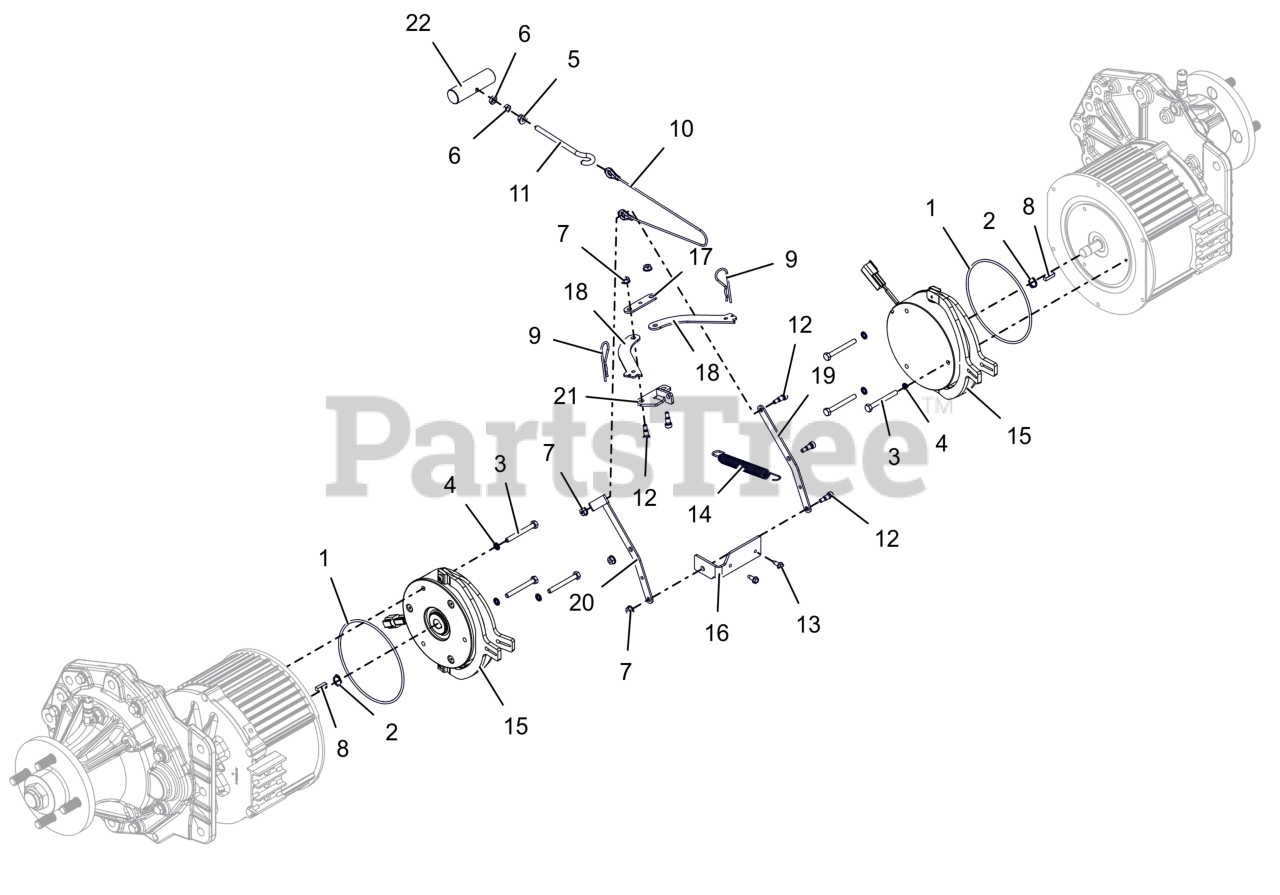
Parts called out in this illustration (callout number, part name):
1	O-RING 126MM IDX3MM
2	RING, RETAINING-EXTERNAL 25MM X 1.2MM
3	BLT,HEX M6-1X55 EP30 G8.8 ZCC
4	WSHR-FL-STL, SEAL 6MMX11MMX1MM
5	NUT-LK-CTR-FLG .25-20 ZC120
6	NUT-JAM .250-20 G2 ZCC
7	NUT, FLG-TOP LK #10-24 GF ZCC
8	KEY-STR 5X5X18MM RD ENDS
9	PIN, HAIR-#7 .094X2.31 ZC120
10	CABLE, LOWER TRACTION (CMPCT)
11	BOLT, EYE .250-20 x 3.00
12	BLT-SHLDR .25X.375
13	SCR,TAP #10-24X.50 HWH TR ZCC
14	SPRING, SWIVEL HOOK EXTENSION
15	BRAKE, MOTOR
16	PIVOT, BRAKE LINK MAIN
17	PLATE, BRAKE PULL DOUBLER
18	LINK, PUSH
19	LINK MIDDLE
20	LINK- MIDDLE
21	LINK- T
22	HANDLE- BRAKE
